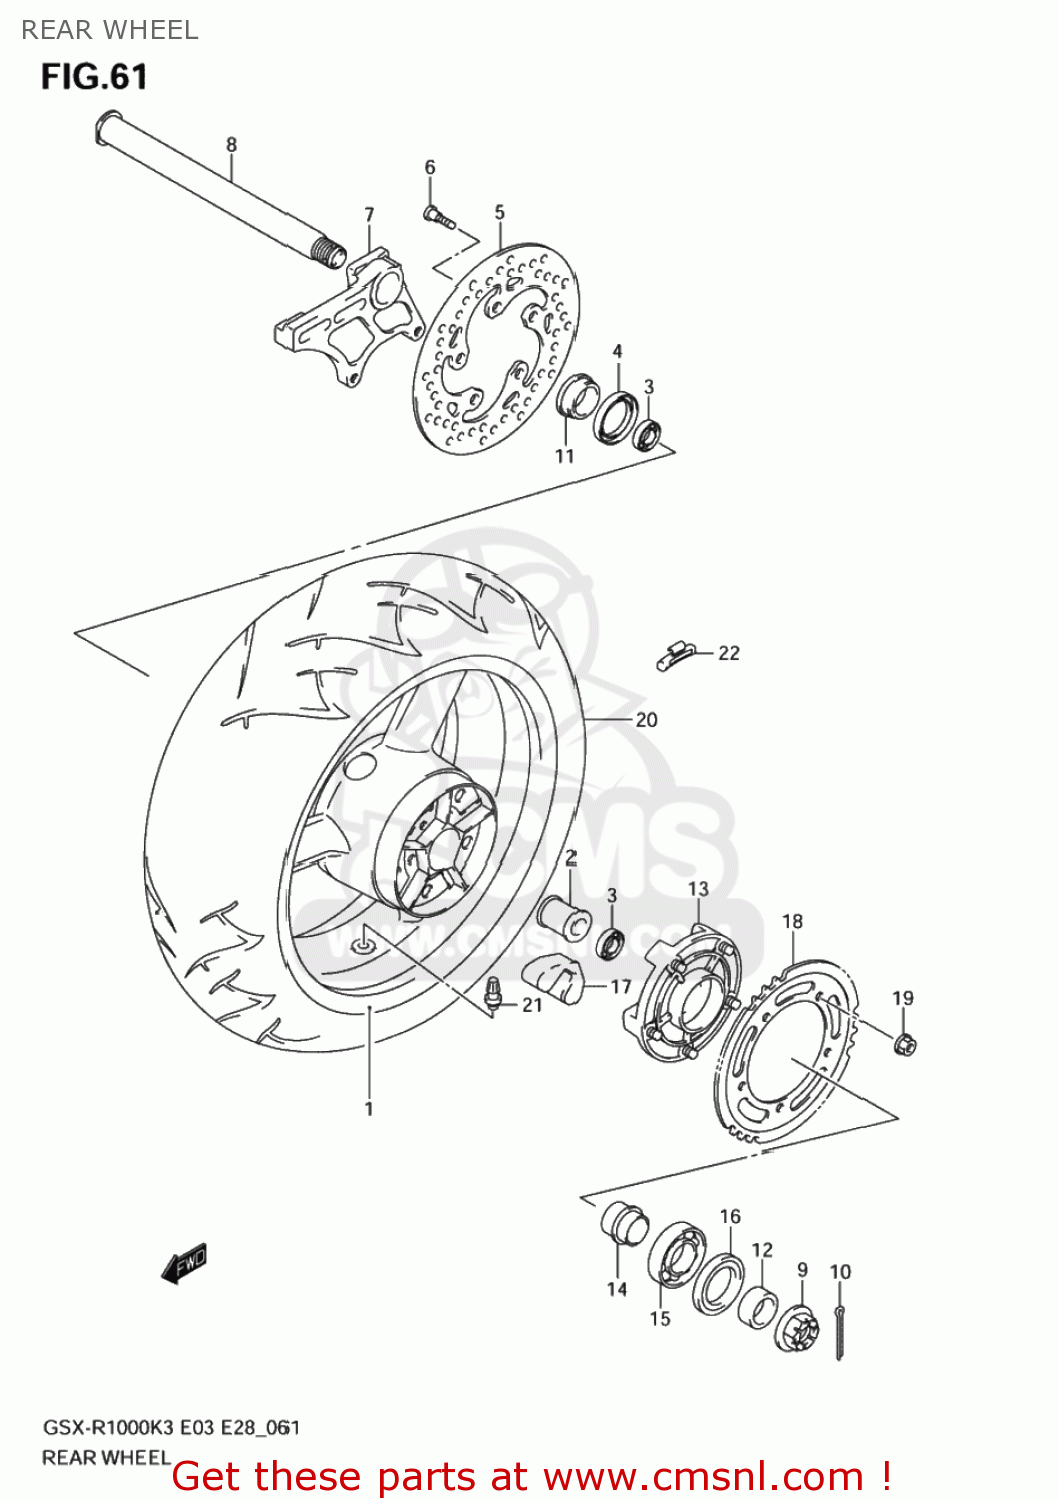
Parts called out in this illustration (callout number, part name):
1	WHEEL,REAR,17X
2	SPACER,RR HUB BEARING
3	BEARING(28X52X12)
4	SEAL,OIL(37X52X8)
5	DISC,RR BRAKE
6	BOLT(8X33)
7	BRACKET,RR CALIPER
8	AXLE,RR
9	NUT
10	PIN, COTTER
11	SPACER,RR AXLE,R
12	SPACER,RR AXLE,L
13	DRUM,RR SPROCKET
14	RETAINER,RR SPROCKET DRUM
15	BEARING
16	SEAL,OIL(39X65X7)
17	ABSORBER,RR HUB SHOCK
18	SPROCKET,RR(42T-530)
19	NUT
20	TIRE COMP,REAR
21	VALVE ASSY,WHEEL RIM(TR412)
22	WEIGHT,WHEEL BALANCE 10G
